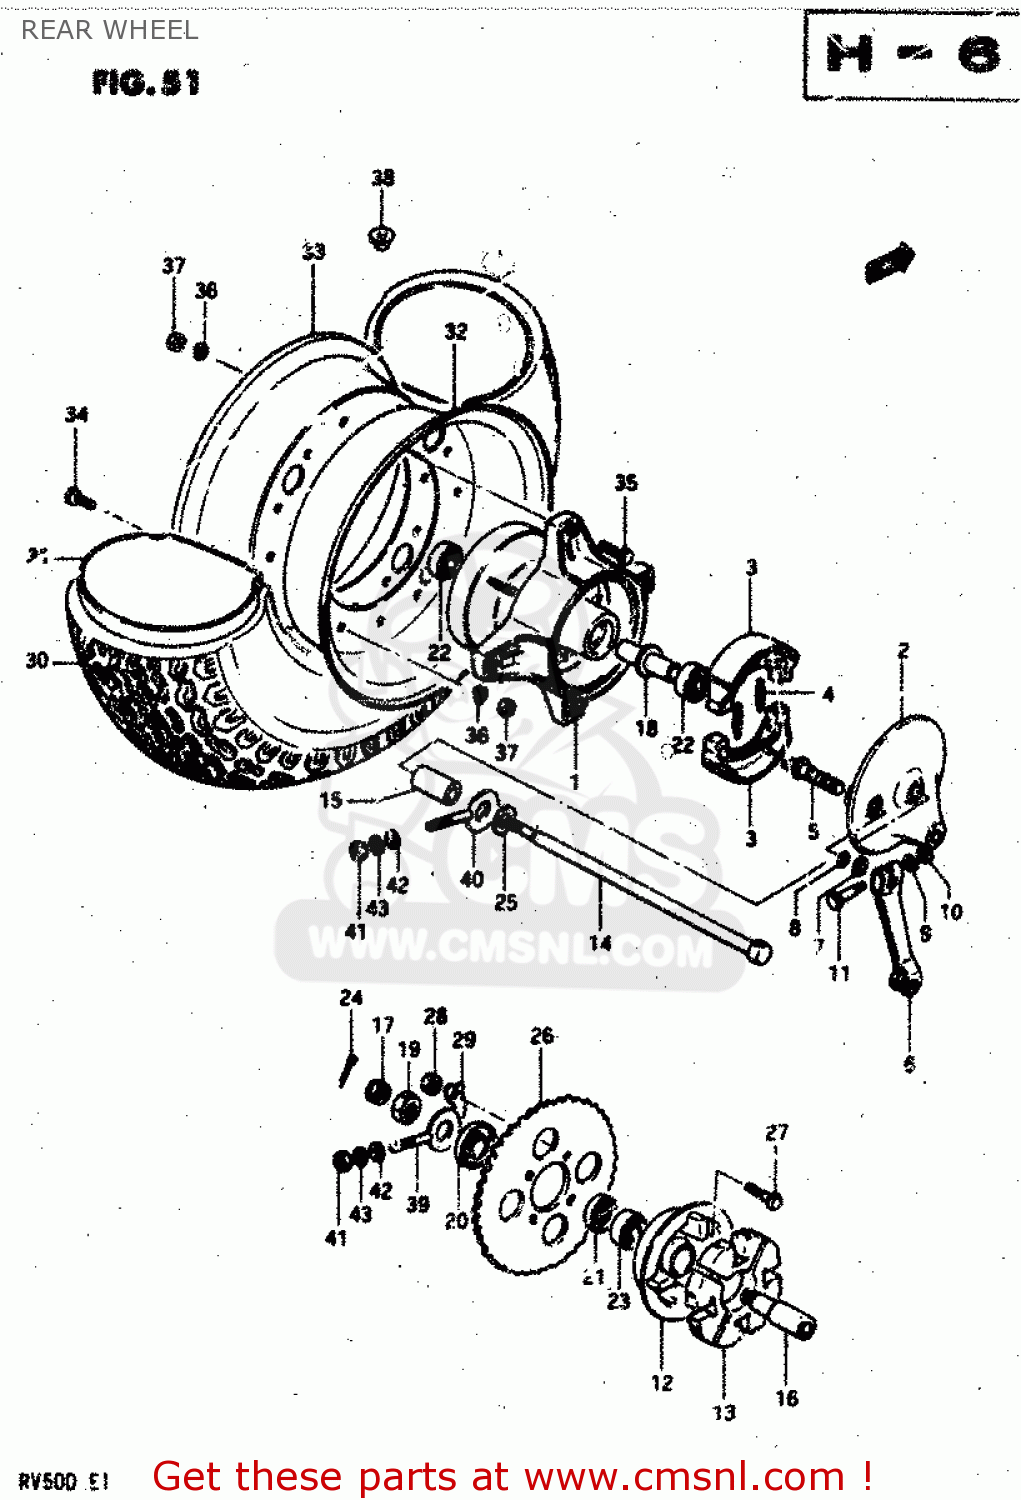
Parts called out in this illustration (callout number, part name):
1	DRUM,REAR HUB
2	PANEL,REAR BRAKE ANCHOR
3	SHOE,BRAKE
4	SPRING(L:34)
5	CAM,FR BRAKE
6	LEVER,REAR BRAKE CAM
7	WASHER(12.5X20X1)
8	O RING(D:2.5,ID:11.4)
9	WASHER
10	NUT
11	BOLT
12	DRUM,REAR SPROCKET MOUNT
13	CUSHION,REAR DRUM
14	AXLE,RR
15	SPACER (12.2X22X37.7)
16	SHAFT,RR SPROCKET DRUM
17	NUT
18	SPACER,REAR HUB BEARING
19	NUT
20	SPACER,REAR SPROCKET DRUM
21	SEAL OIL(25X40X6)
22	BEARING
23	BEARING
24	COTTER PIN
25	WASHER
26	SPROCKET,RR
27	BOLT(8X33.5)
28	NUT
29	WASHER
30	TIRE(5.40 10)
31	TUBE,INNER
32	RIM,WHEEL,R
33	RIM,WHEEL,OUTER
34	BOLT
35	BOLT
36	WASHER,LOCK,8.
37	NUT
38	BUSHING
39	ADJUSTER,CHAIN,R
40	PLATE,CHAIN ADJUSTER
41	NUT
42	WASHER
43	LOCK WASHER
